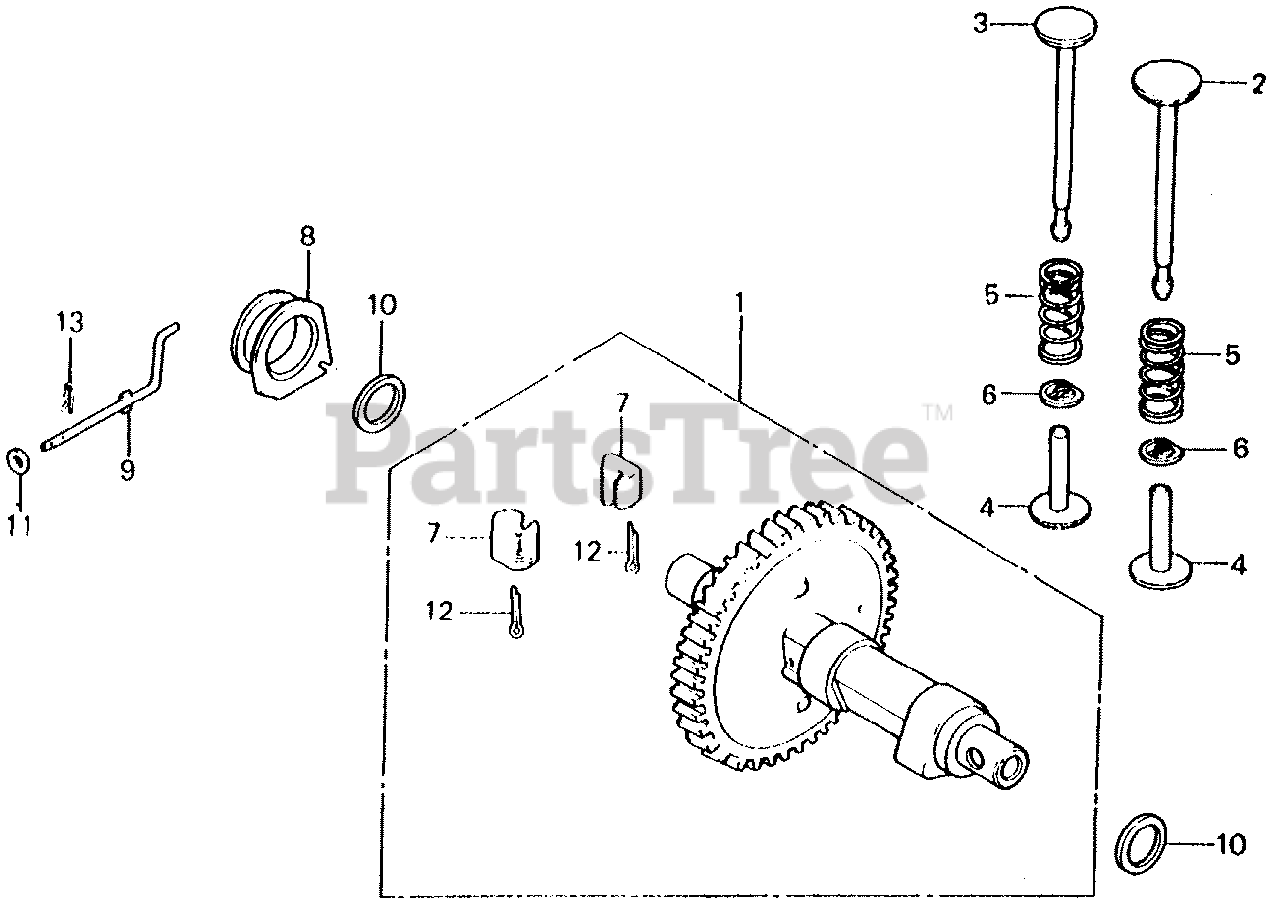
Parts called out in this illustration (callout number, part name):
1	CAMSHAFT ASSY.
2	VALVE, IN.
3	VALVE, EX.
4	LIFTER, VALVE (39.6MM)
4	LIFTER, VALVE (39.9MM)
5	SPRING, VALVE
6	RETAINER, VALVE SPRING
7	WEIGHT, GOVERNOR
8	SLIDER, GOVERNOR
9	SHAFT, GOVERNOR ARM
10	WASHER, THRUST (18MM)
11	WASHER, PLAIN (5MM)
12	PIN, COTTER (3.0X45)
13	PIN, LOCK (8MM)
